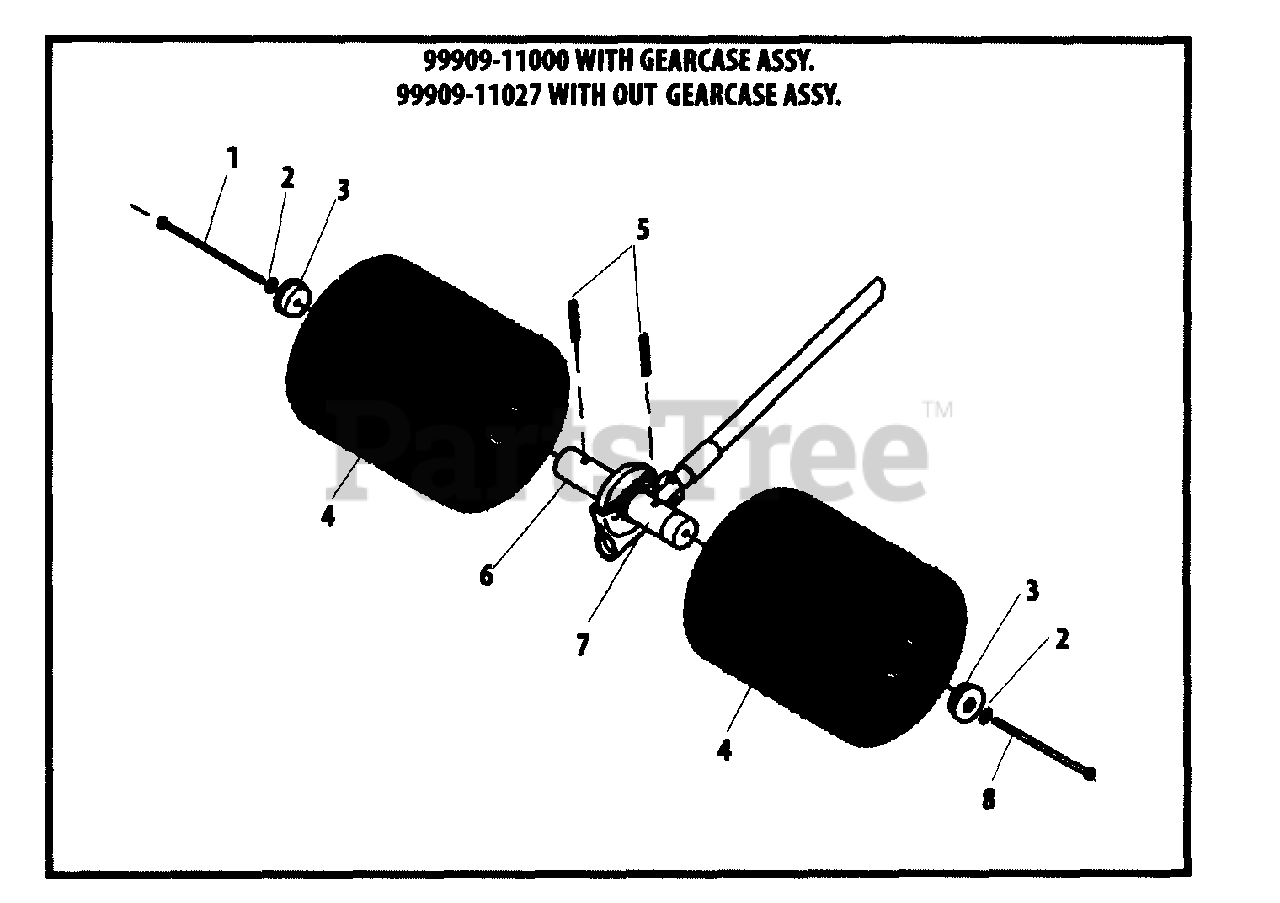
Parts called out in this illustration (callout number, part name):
1	BOLT, BLACK RIGHT HAND TREAD HEX
2	WASHER
3	CAP, END
4	BRUSH, NYLON
5	PIN, ROLLER
6	ADAPTOR, RIGHT HAND THREAD SHAFT
7	ADAPTOR, LEFT HAND THREAD SHAFT
8	BOLT, SILVER LEFT HAND TREAD HEX
